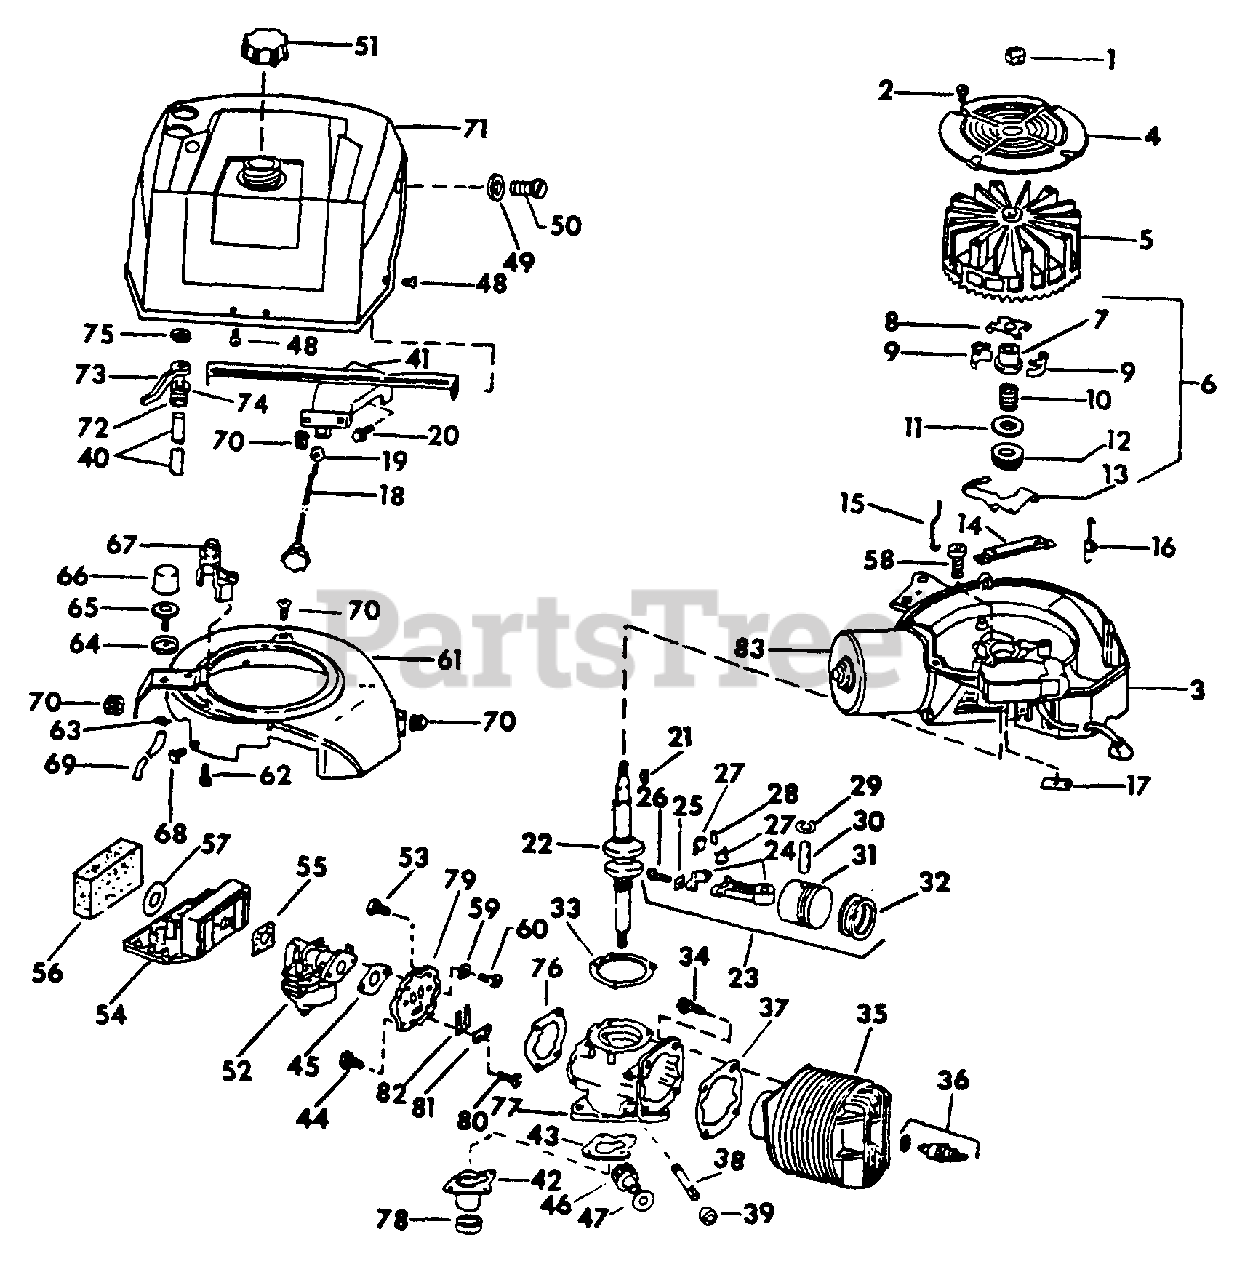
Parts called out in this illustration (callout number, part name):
1	NUT, 7/16-20 HEX.
2	SCREW, 10-24 X 1/2 TRUSS-HD REC TAP
3	MAGNETO ASSY
4	SCREEN, FLYWHEEL
6	GOVERNOR ASSY
7	COLLAR, GOVERNOR
8	YOKE, GOVERNOR
9	WEIGHT, GOVERNOR
10	SPRING, GOVERNOR
11	WASHER, THRUST
12	COLLAR, THRUST
13	LEVER, GOVERNOR
14	BRACKET, GOVERNOR LEVER
15	ROD, GOVERNOR
16	SPRING, VARIABLE SPEED
21	KEY, CRANKSHAFT
23	PISTON & CONNECTING ROD ASSY
24	ROD ASSY, CONNECTING
25	LOCKPLATE, SCREW
26	SCREW, CONNECTING ROD
27	LINER, CONNECTING ROD
28	BEARING SET, NEEDLE
29	RING, RETAINING
32	RING SET, PISTON
33	GASKET, CRANKCASE TO ARM PLATE .010
34	SCREW, CYL TO CRANKCASE
36	SPARK PLUG & GASKET
37	GASKET, CYL TO CRANKCASE
39	SEAL, DRIVE OIL
41	BRACKET, SHROUD
43	GASKET, CRANKSHAFT
44	SCREW, HH REED PLATE TO CRANKCASE
45	GASKET, CARBURETOR
46	GEAR, DRIVESHAFT
47	WASHER, THRUST BRG
48	SCREW, COVER MTG
52	CARBURETOR ASSY
53	SCREW, HH REED PLATE TO CRANKCASE
54	CASE, AIR FILTER
56	ELEMENT, FILTER
58	SCREW, 5/16-18 X 1-1/4 ZND HEX-HD CAP
61	BAFFLE, BRACKET
67	BRACKET & EYELET
70	GROMMET, COVER MTG
71	SHROUD, TANK & VALVE ASSY
72	CLIP, SPRING
76	GASKET, REED PLATE
77	CRANKCASE AND SEAL ASSY
79	REED PLATE ASSY
80	SCREW, 6-32 X 1/4 C-Z SLT RD-HD
81	PLATE, BACKUP
83	STARTER ASSY, ELECTRIC
